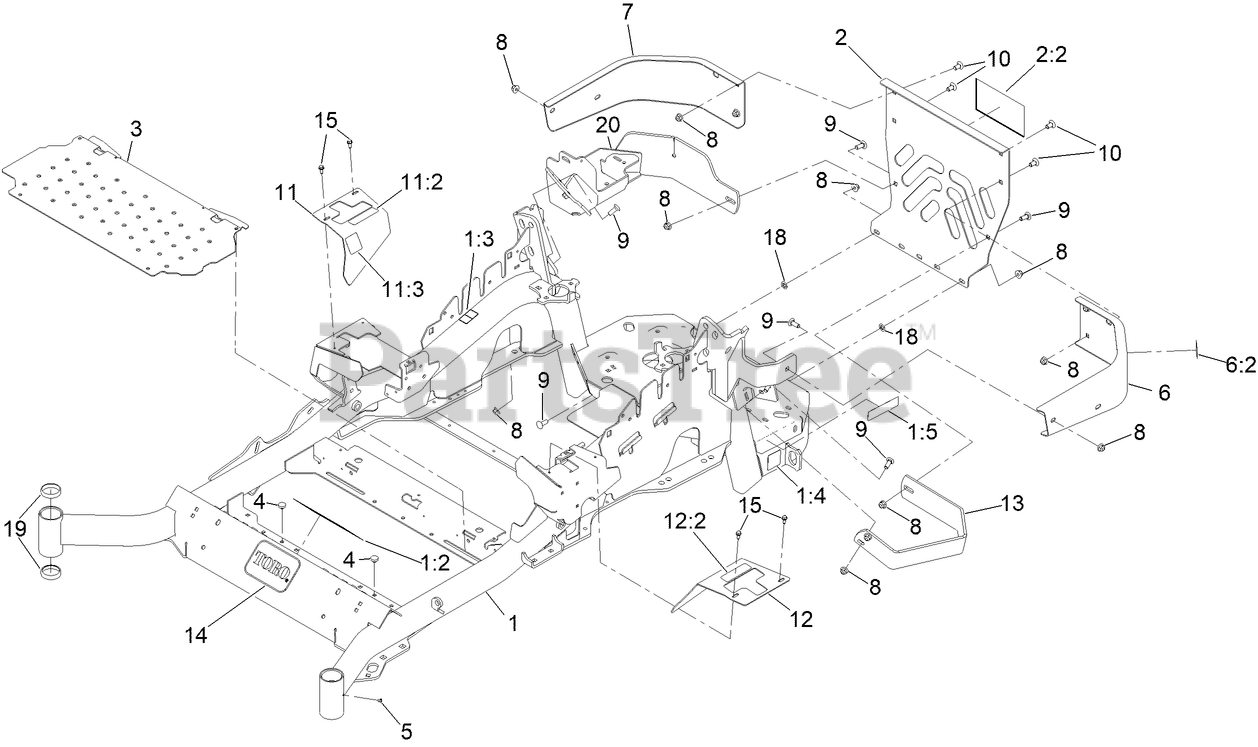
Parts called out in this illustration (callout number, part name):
1	MAINFRAME SERVICE ASM - 60
1:2	DECAL-DANGER
1:3	DECAL-WARNING
1:4	DECAL-HAZARD, PINCHED FINGER
1:5	DECAL-ARRESTOR, SPARK
2	REAR GUARD ASM
2:2	DECAL
3	FLOORPAN
4	BUMPER
6	LH BUMPER ASM
6:2	DECAL-WARNING
7	BUMPER-RH
8	NUT-HF, NI
9	SCREW-CARR
10	SCREW-CARR
11	RH MOTION CONTROL COVER ASM
11:2	DECAL-CONTROL, MOTION
11:3	DECAL-PARK BRAKE, CE
12	LH MOTION CONTROL COVER ASM
12:2	DECAL-CONTROL, MOTION
13	GUARD-MUFFLER
14	DECAL
15	SCREW-HWH
18	NUT-PUSH
19	CUP-BEARING
20	BATTERY GUARD ASM
